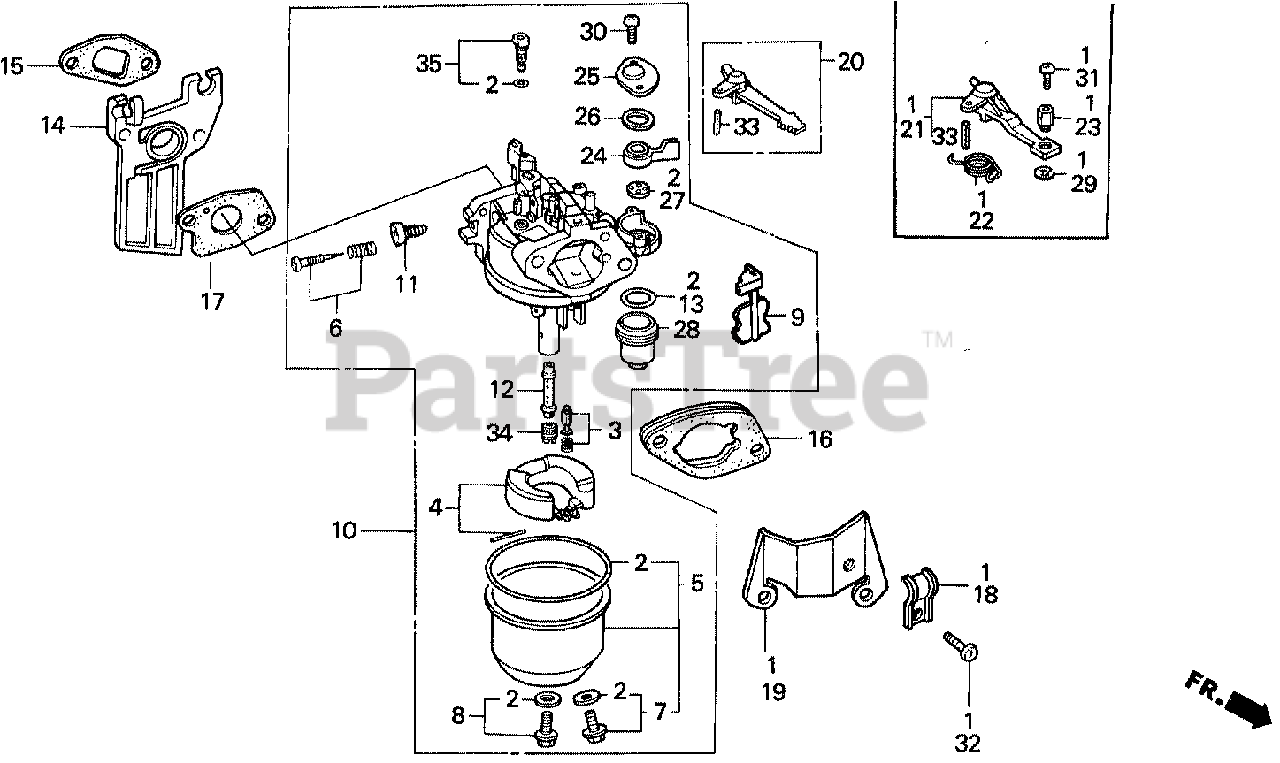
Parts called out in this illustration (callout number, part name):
2	GASKET SET
3	VALVE SET, FLOAT
4	FLOAT SET
5	CHAMBER SET, FLOAT
6	SCREW SET, PILOT
6	SCREW SET
7	SCREW SET, DRAIN
8	SCREW SET B
9	CHOKE SET
10	CARBURETOR ASSY. (BE65C B)
10	CARBURETOR ASSY.
11	SCREW, THROTTLE STOP
12	NOZZLE, MAIN
13	GASKET, FUEL STRAINER CUP
14	INSULATOR, CARBURETOR
15	GASKET, INSULATOR
16	SPACER, CARBURETOR
17	GASKET, CARBURETOR
20	LEVER, CHOKE (STD)
24	LEVER, VALVE
25	PLATE, LEVER SETTING
26	SPRING, VALVE LEVER
27	GASKET, VALVE
28	CUP, FUEL STRAINER
30	SCREW, PAN (3X6)
30	SCREW, PAN (3X8)
33	PIN, SPRING (2X12)
34	JET, MAIN (#68)
34	JET, MAIN (#70)
34	JET, MAIN (#72)
35	JET SET, PILOT (#35)
35	JET SET, PILOT (#38)
